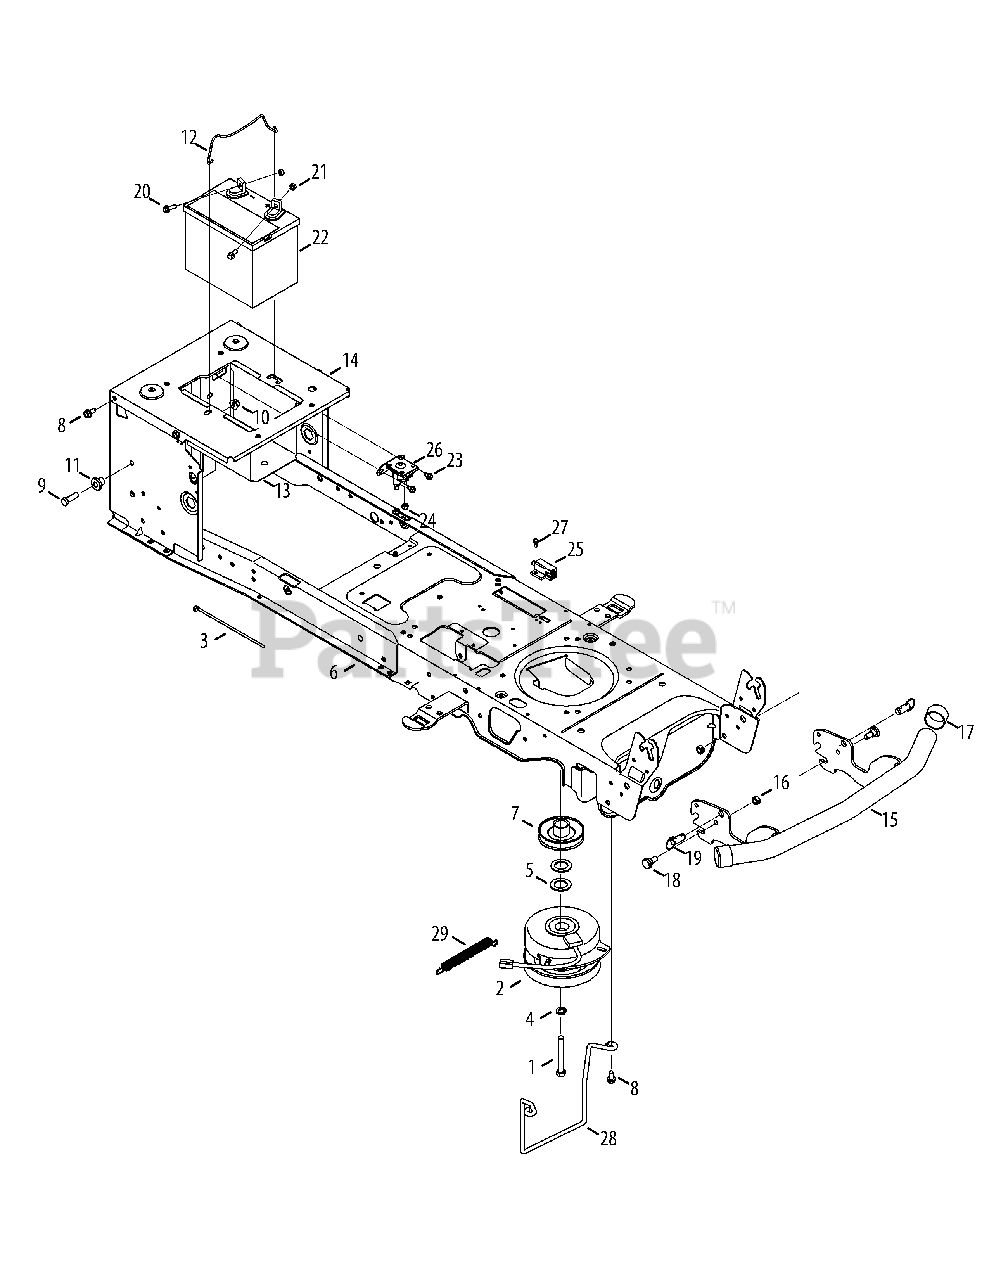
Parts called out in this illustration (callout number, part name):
1	Hex Head Screw, 7/16-20x3.50
2	Electric PTO Clutch
3	Cable Tie, 3/16 x .05 x 7.4
4	Lock Washer, 7/16
5	Flat Washer, 1.031 x 1.620 x .095
6	Frame
7	Electric PTO Engine Pulley
8	Taptite Screw, 5/16-18x.750
9	Hex Head Screw, 3/8-16x1.25
10	Flangelock Nut, 3/8-16
11	Shoulder Spacer, .38 x 1.0 x .70
12	Battery Holder Rod
14	Seat Frame Bracket
16	Hexlock Nut, 3/8-16
17	Bumper Cap
18	Shoulder Bolt, .496 x .336
19	Quick Release Pin
20	Hex Head Flange, 1/4-20x.75
21	Sems Nut, 1/4-20
23	Taptite Screw, 1/4-20x0.375
24	Flangelock Nut, 1/4-20
25	Interlock Switch
26	Solenoid, 12 V
27	Shoulder Screw, #10-32x.500
28	Belt Keeper Rod
29	Spring, Extn, .56 Dia X 5.52
